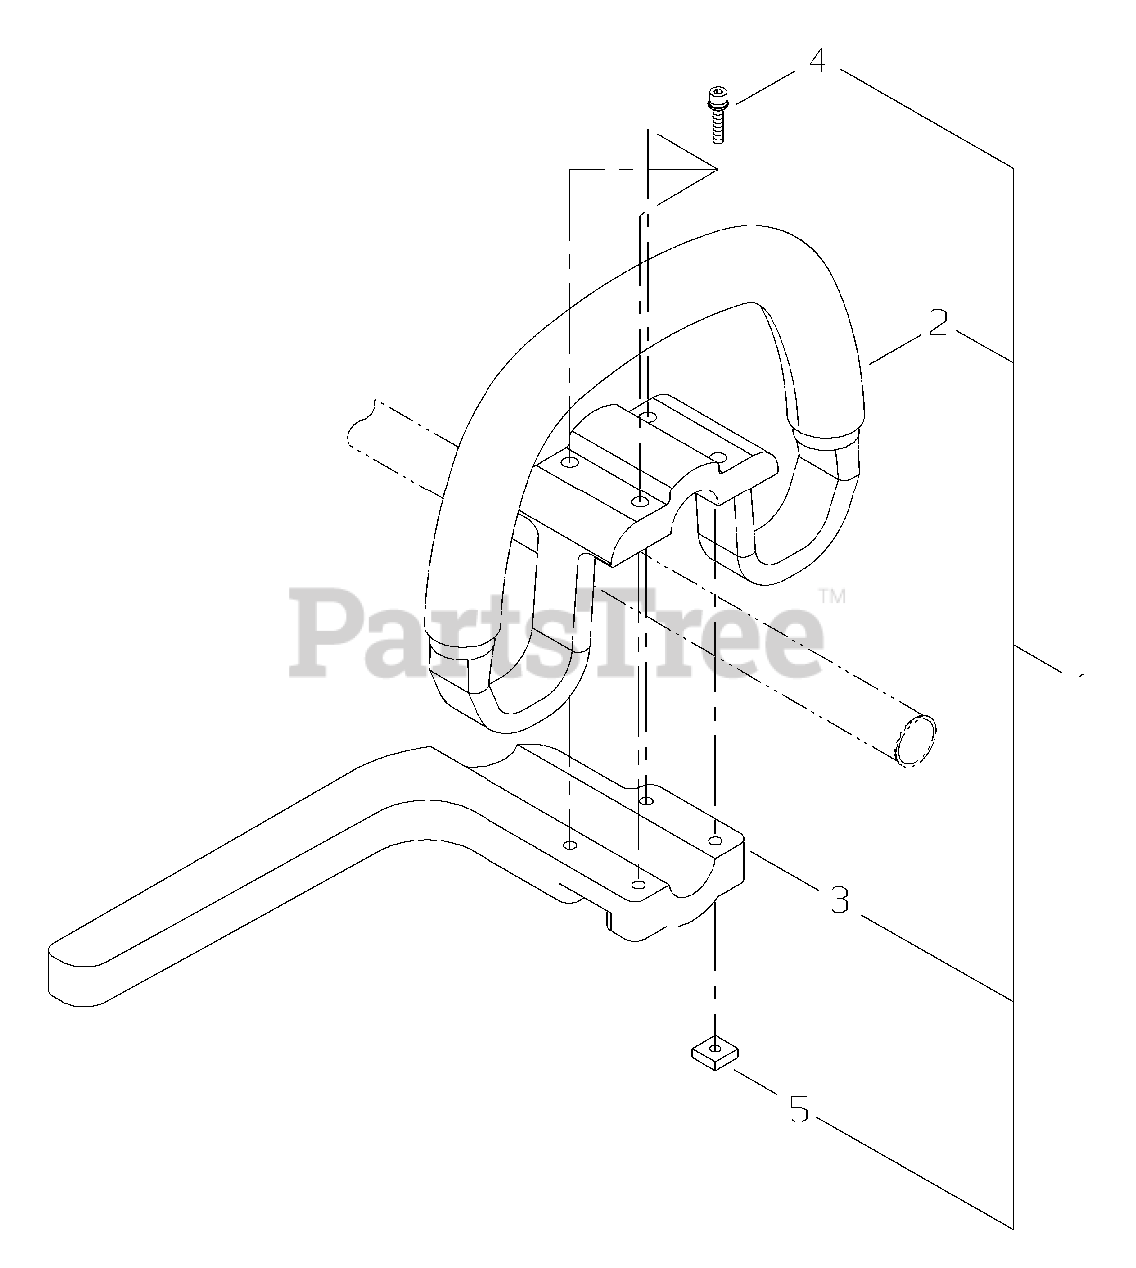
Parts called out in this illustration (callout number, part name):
1	HANDLE ASSY
2	HANDLE
3	BARRIER
4	SCREW - 5X35
5	NUT - 5
